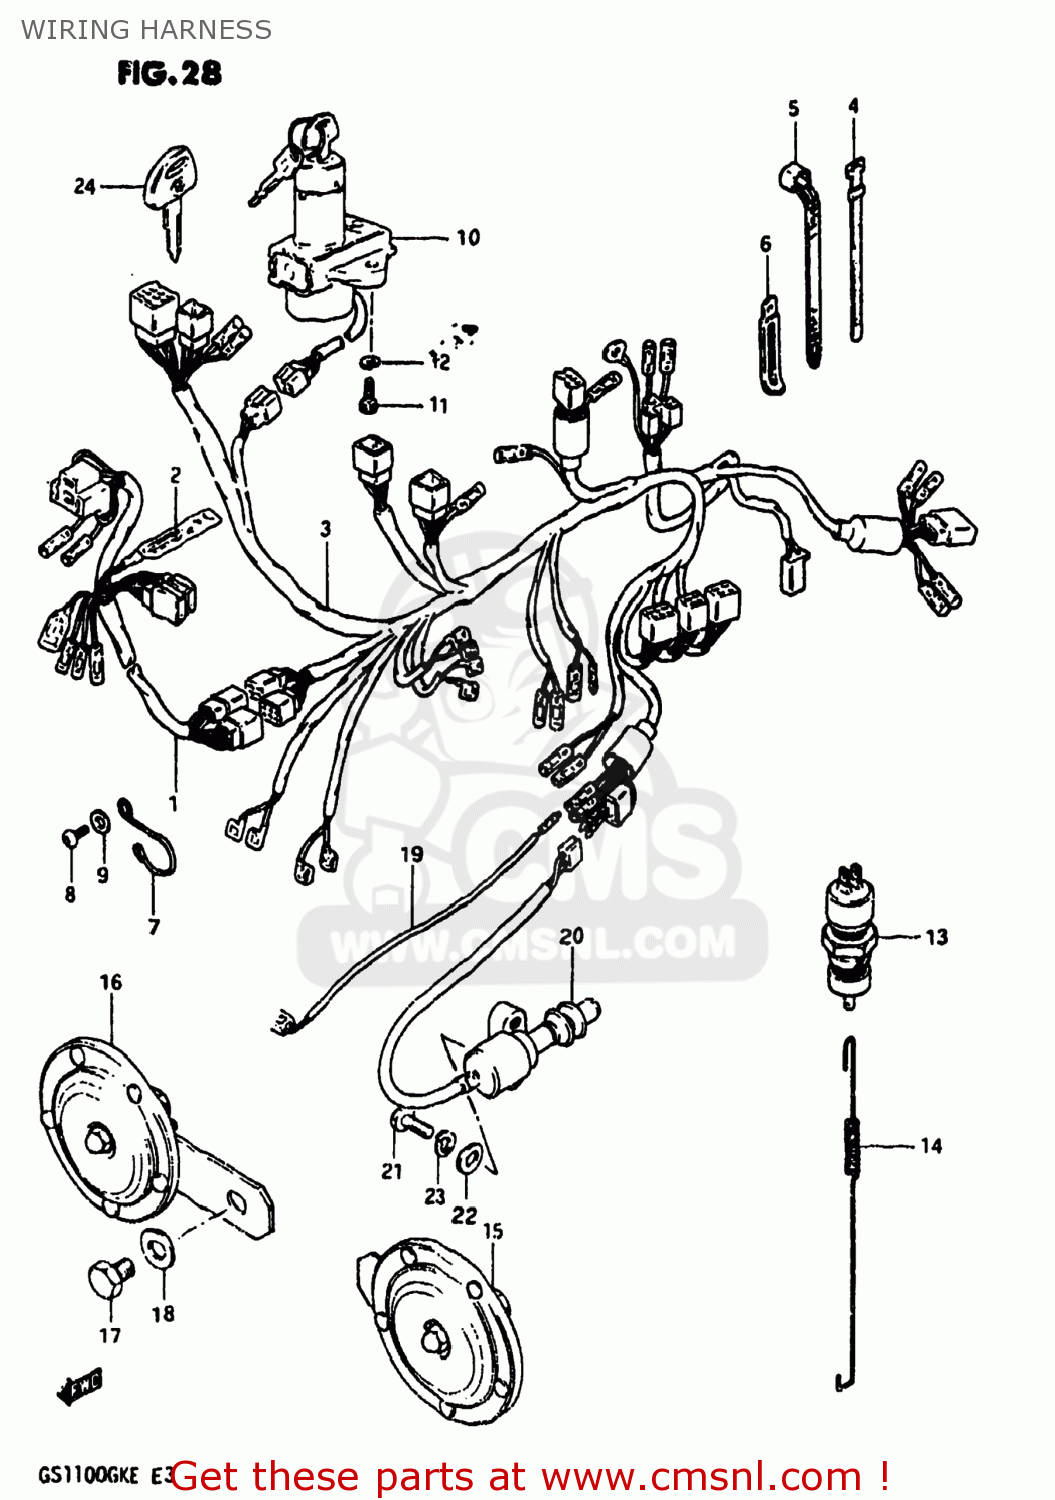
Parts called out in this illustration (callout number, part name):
1	HARNESS,WIRING NO.1
2	DIODE
3	HARNESS,WIRING NO.2
4	CLAMP(L:120)
5	CLAMP(L:125)
6	CLAMP
7	CLIP,WIRING HARNESS
8	SCREW
9	WASHER
10	SWITCH ASSEMBLY,IGNITION
11	BOLT
12	LOCK WASHER
13	SWITCH ASSEMBLY,STOP LAMP
14	SPRING
15	HORN ASSEMBLY,LOW PITCH
16	HORN ASSEMBLY,HIGH PITCH
17	BOLT
18	WASHER,8.5X16X
19	WIRE,OIL PRESSURE SWITCH LEAD
20	SWITCH ASSEMBLY,SIDE STAND
21	BOLT
22	WASHER
23	LOCK WASHER
24	KEY,BLANK
